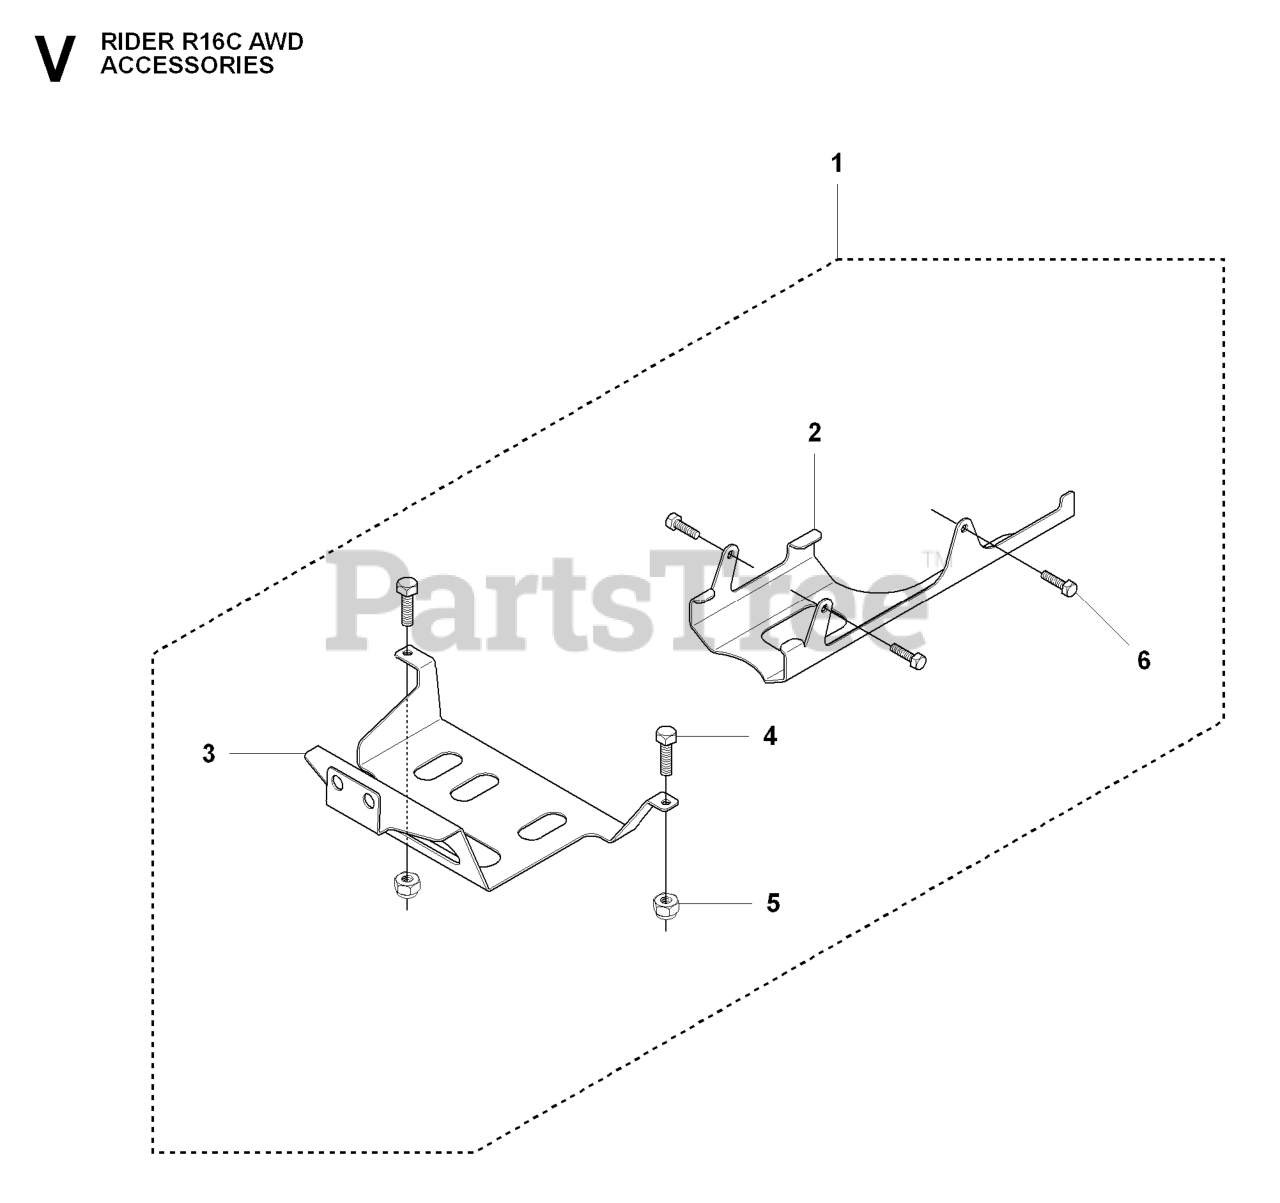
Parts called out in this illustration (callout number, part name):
1	AXLE PROTECTION KIT (R322T)
3	RP PROTECTION PLATE REAR
5	LOCKNUT M8
6	BOLT FLANGE - M8X16
